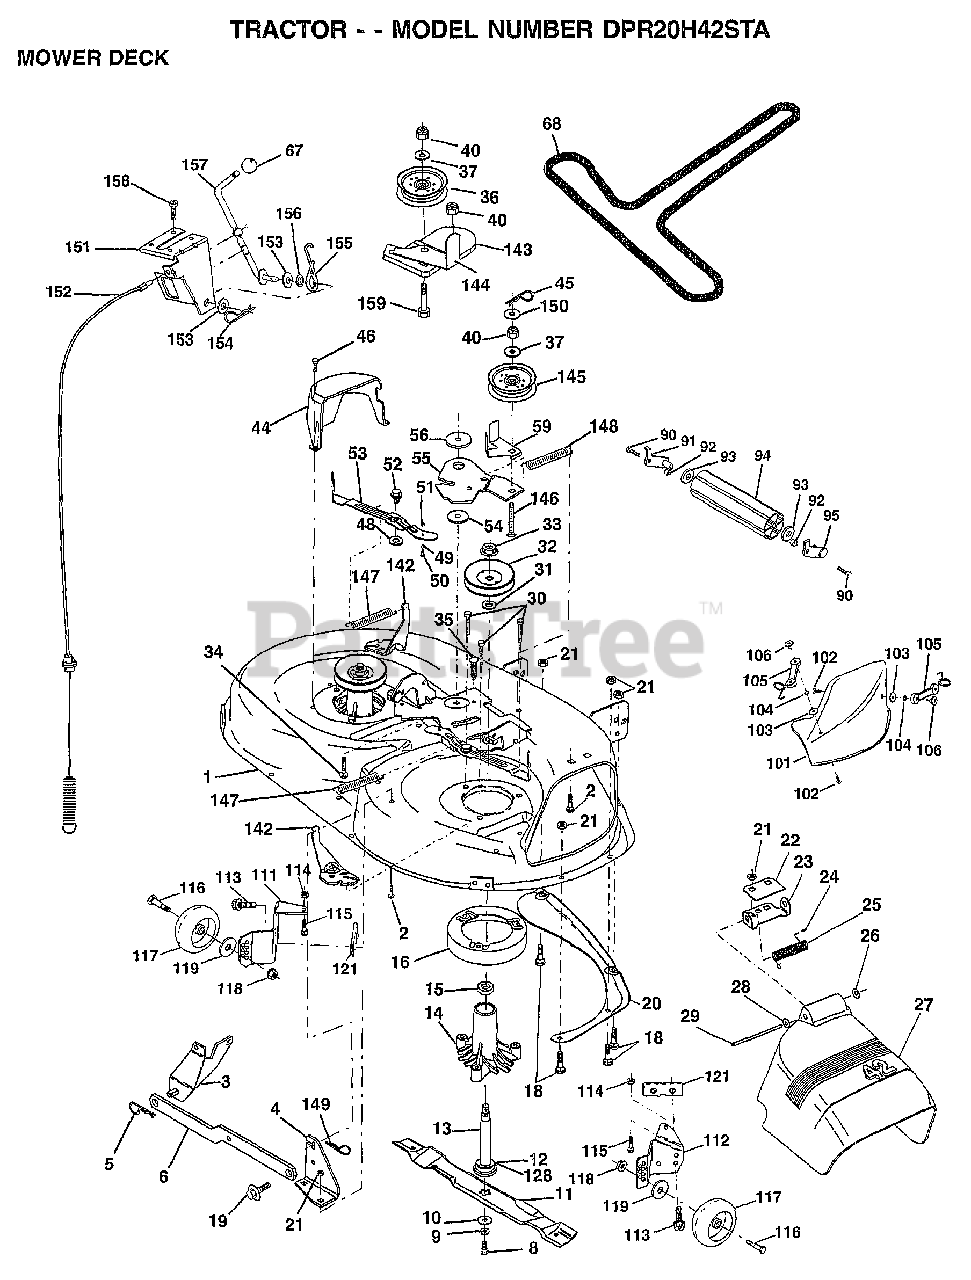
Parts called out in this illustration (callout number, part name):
1	MOWER DECK ASSEMBLY
2	BOLT
3	BRKT ASM SWAY BAR
4	BRACKET ASSY DECK
8	BLADE BOLT
10	WASHER.HARD.BLADE
11	"BLADE.42"" MULCHER"
11	"BLADE.42"" HIPERF"
12	BEARING.BALL
14	HSG ASM MANDREL
15	BEARING
16	STRIPPER RND MWR
18	BOLT
19	BOLT SHD 5/16-18
20	BAFFLE VORTEX 42
22	STIFFENER BRACKET
23	BRACKET DEFLBRACKET DEFLECTOR MOWER 42''
24	CAP-SLEEVE LT
25	SPRING TORSION
26	NUT PUSH M
27	SHIELD DEFLECTOR 42''
28	WASHER
29	HINGE ROD
30	"SCREW-THD ROLL,WA"
31	WASHER
32	PULLEY
34	BOLT
35	XMAS TREE FASTNER
36	PULLEY
37	WASHER
44	GUARD MAND LH BLK
45	RETAINER M
46	SCREW.1/4-20X5/8
48	HARD SMALL WASHER
49	ROLLER ASM-CAM
50	SHOULDER BOLT
51	LOCKNUT
52	BOLT.SHLD.5/16-18
53	BRAKE PAD ARM ASM
54	HARDENED WASHER
55	ARM, IDLER
56	SPACER RETAINER
59	GUARD TUV IDLER
67	KNOB
68	BELT-V.SEC.46.KEL
90	BOLT
92	NUT
93	WASHER
101	"COVER.MULCH.42"""
102	SCREW
103	WASHER #10
104	LOCKWASHER
105	LATCH ASSY.BAGGER
106	WELDNUT
111	BRACKET
112	BRACKET
113	SCREW
116	BOLT M
117	WHEEL.GUAGE
118	LOCKNUT
119	WASHER
121	BRACKET.EXTRD.GWL
128	WASHER.FELT.
142	ARM SPRING BRAKE MOWER
143	BRACKET ARM IDLER 42''
144	KEEPER BELT 42'' CLUTCH CABLE
145	PULLEY IDLER FLAT
146	BOLT
147	SPRING EXTENSION
148	SPRING RETURN IDLER
149	RETAINER SPRING
150	WASHER PM
151	BRKT CLUTCH CABLE
152	"CABLE.CLUTCH.42"""
153	WASHER FLAT
154	SPRING RETAINER
155	SPRING RETENTION LVR CLUTCH CAB
156	SPACER
157	ROD.CLUTCH.CABLE.3/8
158	SCREW LT
159	BOLT
